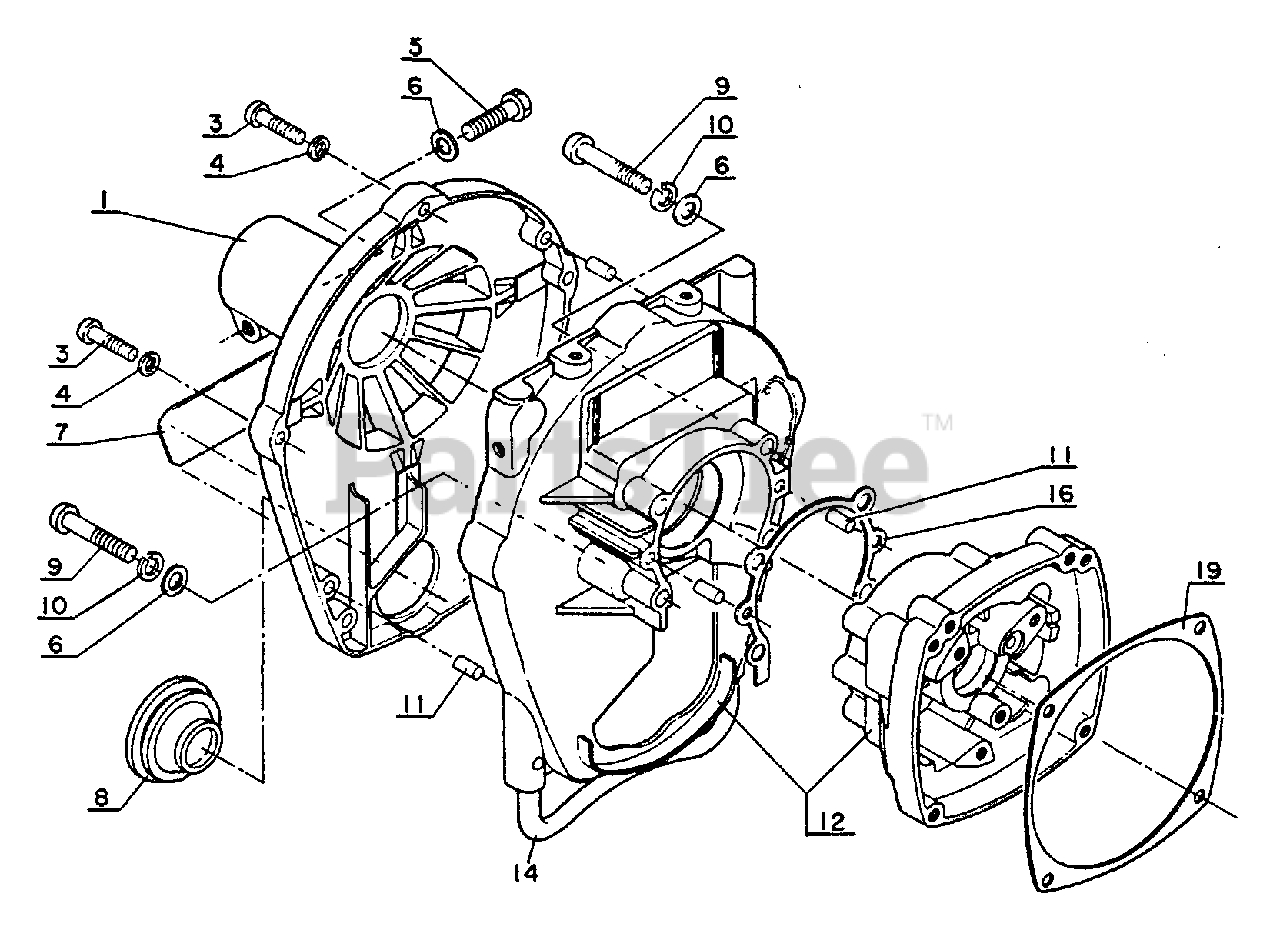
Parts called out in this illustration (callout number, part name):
1	CASE, FAN
3	SCREW 4×18
4	WASHER 4 MM
5	BOLT - 5×20
6	WASHER, FLAT 5.5×10×0.8
7	MODEL PLATE
8	COVER, SPARK PLUG
9	SCREW 5×30
10	WASHER, SPRING 5
11	PIN, LOCATING 4
12	CRANKCASE KIT
14	STAND
16	GASKET, CRANKCASE
19	GASKET, STARTER
